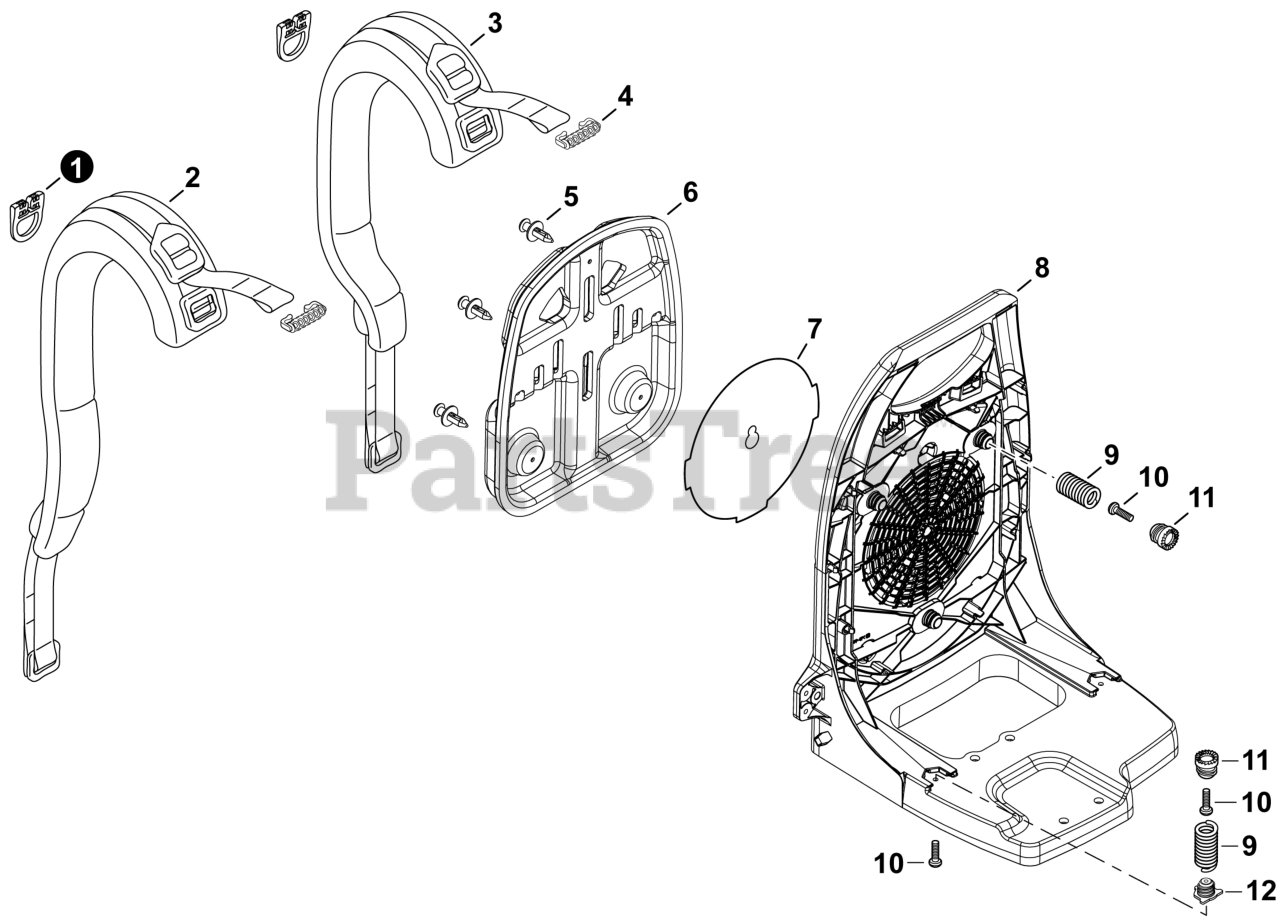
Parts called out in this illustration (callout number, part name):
1	BUCKLE, HARNESS
2	SHOULDER STRAP - LEFT
3	SHOULDER STRAP - RIGHT
6	CUSHION, BACKPACK
7	INSERT, COLD WEATHER
8	FRAME, BACKPACK
9	SPRING, COMPRESSION
10	BOLT, TORX 5x20
11	HOLDER, SPRING
12	HOLDER, SPRING
